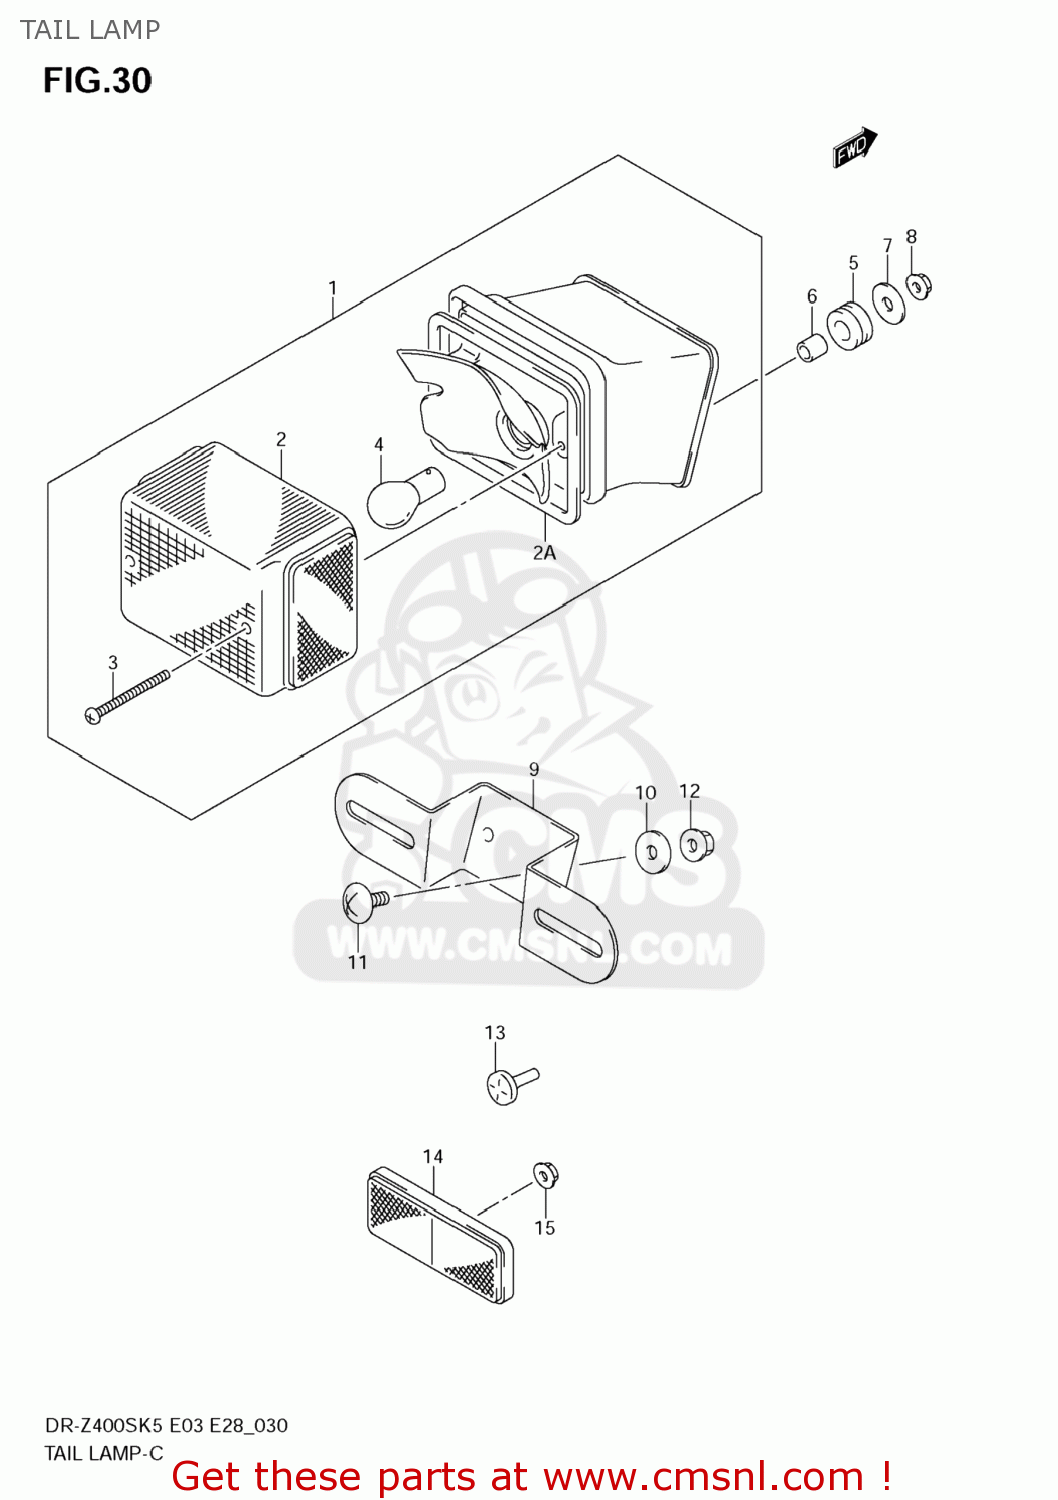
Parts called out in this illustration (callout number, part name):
1	LAMP ASSY,RR COMBINATION
2	LENS
2A	GASKET,LENS (NAS)
3	SCREW(4X45)
4	BULB(12V21/5W)
5	CUSHION
6	SPACER(6.5X10X10)
7	WASHER(6.5X20X1.6)
8	NUT
9	BRACKET,LICENSE PLATE
10	WASHER(6.5X20X1.6)
11	SCREW
12	NUT
13	CUSHION
14	REFLECTOR ASSY,RR
15	NUT
